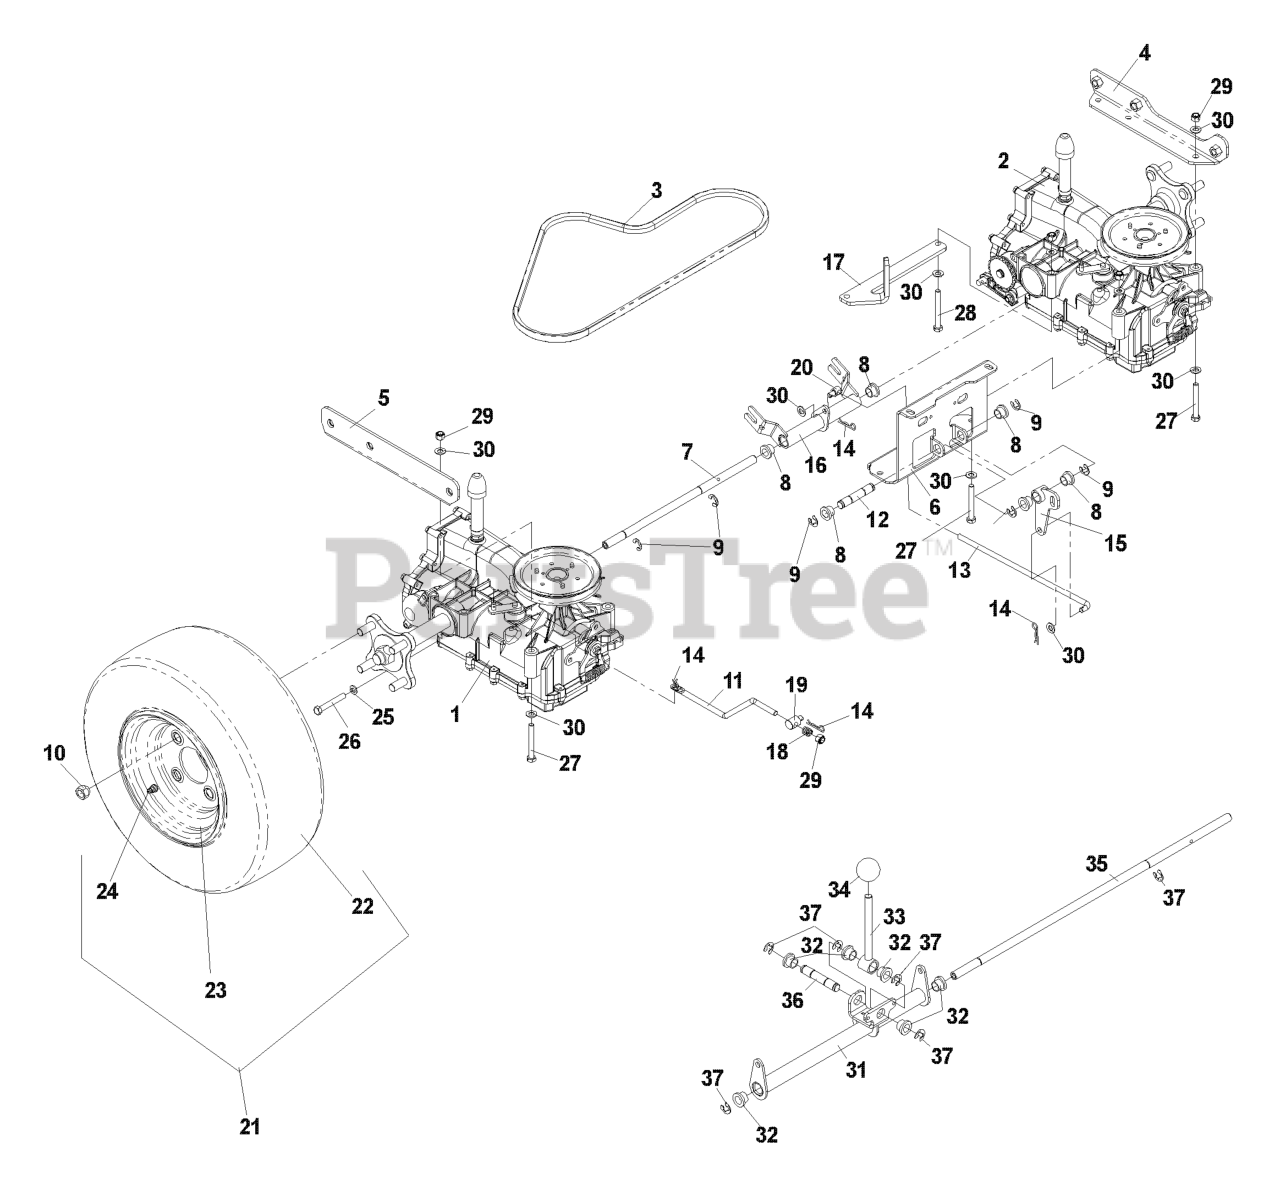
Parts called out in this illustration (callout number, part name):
1	HG_IZT LEFT (354-2400R)
1	HG_IZT LEFT
2	HG_IZT RIGHT (354-2400L)
2	IZT RIGHT
4	IZT SUPPORT RIGHT
5	IZT SUPPORT, LT
6	IZT SUPPORT, REAR
7	IZT CONNECTOR
8	BUSHING, FLANGED NYLON
9	E-RING 1/2 (2 2)
10	LUG NUT 1/2F
11	IZT BYPASS LINKAGE
13	BRAKE LINKAGE
14	HAIRPIN #2
15	BRAKE BELLCRANK, REAR
16	BRAKE BELLCRANK, FRONT
17	CLUTCH TIE DOWN
20	SWIVEL (SHORT)
21	TIRE/WHEEL.ASSEM.16X6.5-8.ZTR
22	TIRE, 16/650-8 TURF RIDER
24	VALVE STEM TR-412
25	WASHER.LOCK.HVY.HLCL.SPR.5/16
26	HEX SCREW-.313C X 2.25 GR8
27	BOLT 5/16C X 2 1/2
28	HCS 5/16C X 2-3/4
29	NUT 5/16 NYLOC
30	FLAT WASHER 5/16 SAE
31	ACTUATOR ARM
32	BUSHING, FLANGED NYLON
37	E-RING 1/2 (2 2)
